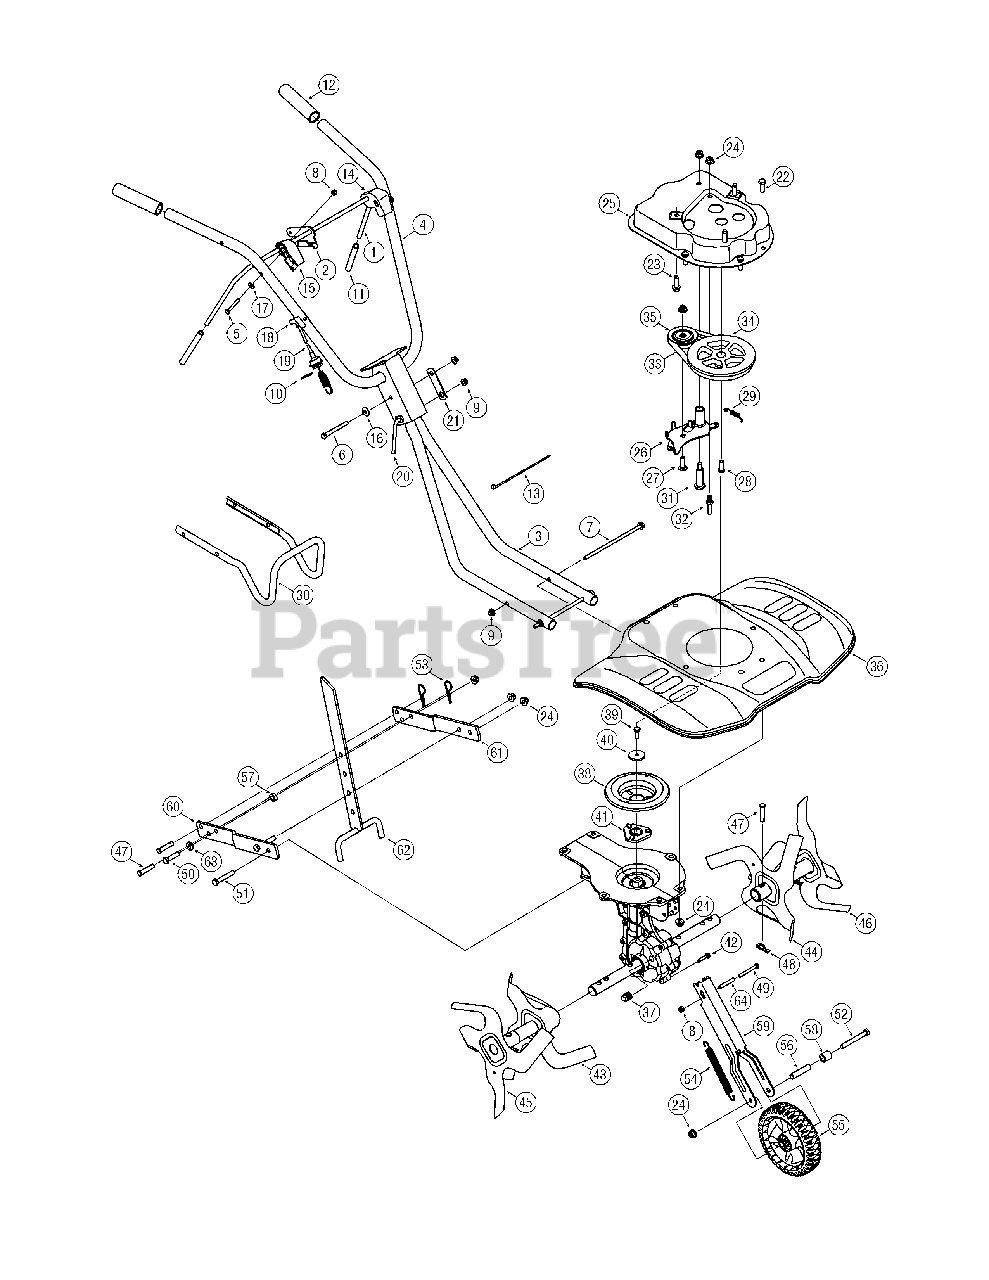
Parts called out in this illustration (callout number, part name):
1	Clutch Bail
5	Hex Screw: 1/4-20:1.75:GR5:STD
6	Hex Screw: 5/16-18:3.00:GR5:STD
7	Flange Screw: 5/16-18:7.500:GR5
8	Hex Lock Nut: 1/4-20:GR8:NYL
9	Flange Lock Nut:5/16-18:GRF:NYL
10	Snap Ring: 1.0 dia. shaft
11	Handle Grip
12	Grip: 1.0 ID x 5.0 LG
13	Cable Tie
14	Bail Holder LH
15	Bail Holder RH
16	Bell Washer: .340 x .872 x .060
17	Flat Washer: .25 x .630 x .0515
18	Snap Fitting
19	Forward Clutch Cable
20	Handle Adjustment Lever
21	Retainer Bracket
22	Hex Screw: 3/8-16:1.00:GR5:STD
23	TT Screw: 3/8-16:1.250
24	Flange Lock Nut: 3/8-16:GRF:NYL
26	Idler Assembly Forward
27	Shoulder Screw: 3/8-16:1.25:GR5
28	Socket Screw: 3/8-24:1.0
29	Extension Spring
31	Shoulder Screw: .56 x 1.87:3/8-16
32	Stud: .33 x 1.5:3/8-16
34	Flywheel Pulley
35	Idler Pulley
37	Pipe Plug: 3/8 NPT
38	Pulley
39	Socket Screw: 3/8-24:1.0
40	Bell Washer: .382 x 1.500 x .109
41	Pulley Adapter: .9875 dia.w/dd
42	TT Screw: 1/4-20:1.250
47	Clevis Pin
48	Internal Cotter Pin
49	Hex Screw: 1/4-20:2.25:GR5:STD
50	Hex Screw: 3/8-16:1.50:GR5:STD
51	Hex Screw: 3/8-16:2.25:GR5:STD
52	Hex Screw: 3/8-16:3.25:GR8:STD
53	Internal Cotter Pin
54	Extension Spring
55	Wheel 7 x 1.8
56	Tube Sleeve
57	Spacer: .383 x .750 x .285
58	Spacer: .525 x .775 x .835
64	Tube Sleeve
